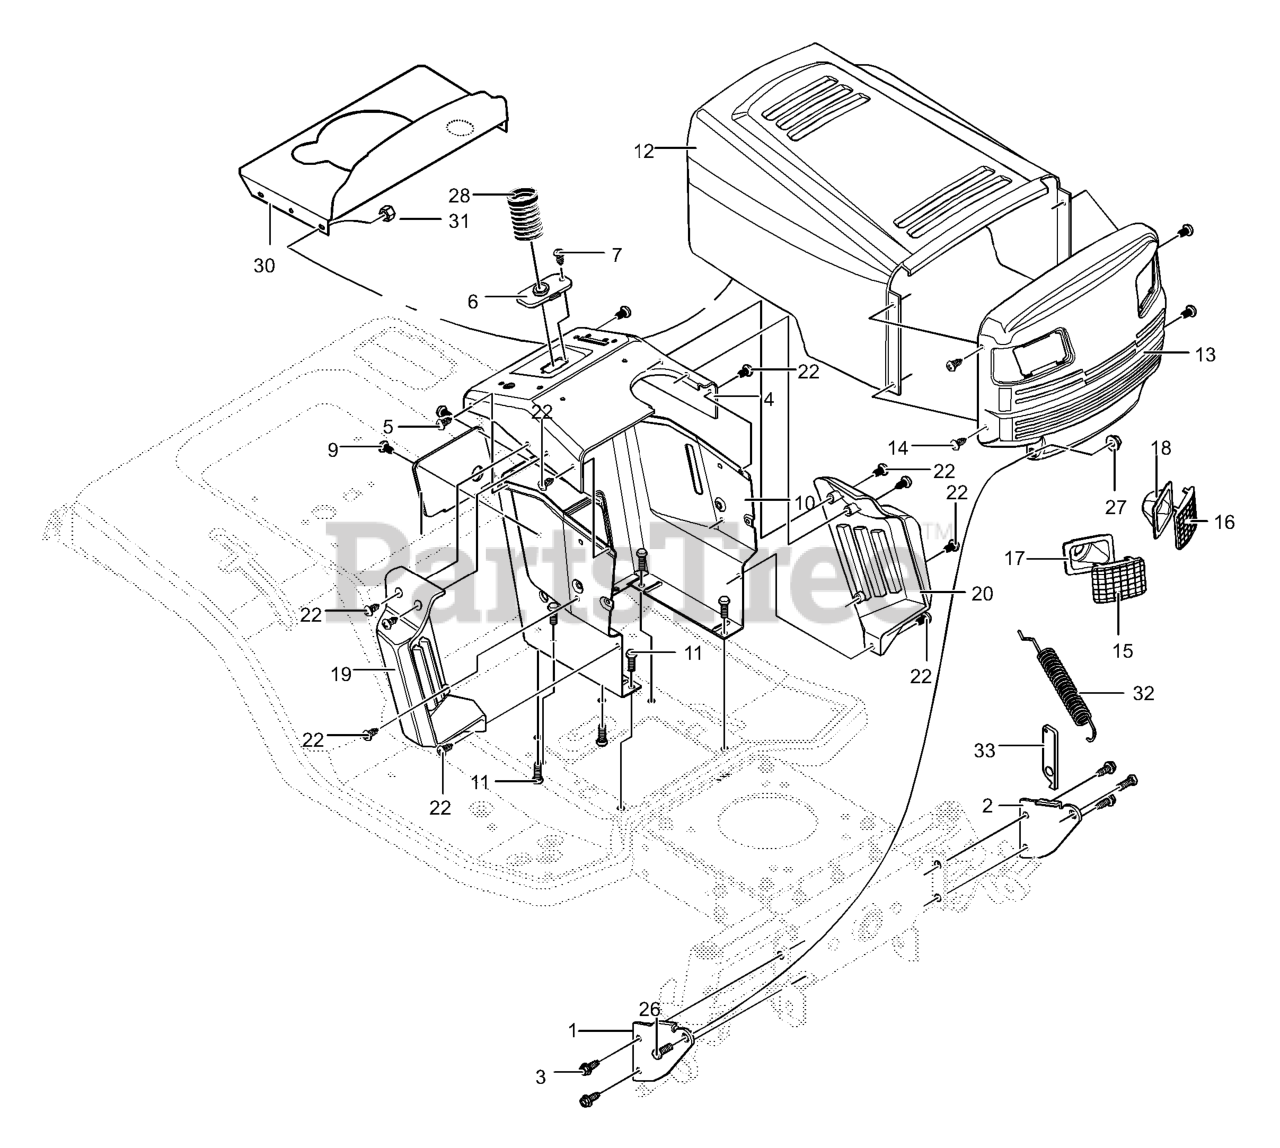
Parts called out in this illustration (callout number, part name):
1	SUPPORT, GRILLE RH
2	SUPPORT, GRILLE LH
3	SCREW, 5/16-18 x 0.75
5	SCREW, 10-24X.500
6	STEERING BRACKET
7	SCREW, 1/4-20X.50
8	PANEL, ACCESS W/BUZZER
9	SCREW, 10-24X.500
10	DASH SUPPORT
11	SCREW, 5/16-18 x 0.75
14	SCREW, 10-24X.500
15	LENS, TWIN RH
16	LENS, TWIN LH
17	REFLECTOR, RH
18	REFLECTOR, LH
19	PANEL, SIDE RH
20	PANEL, SIDE LH
22	SCREW, 10-24X.500
26	BOLT, SHOULDER .375
27	NUT, 3/8-16
28	BELLOWS-STEERING POST
29	PAD, ADHESIVE
31	NUT, 1/4-20 HEXNYL
32	SPRING, EXT. 5.13LG
33	BRACKET, HOOD
